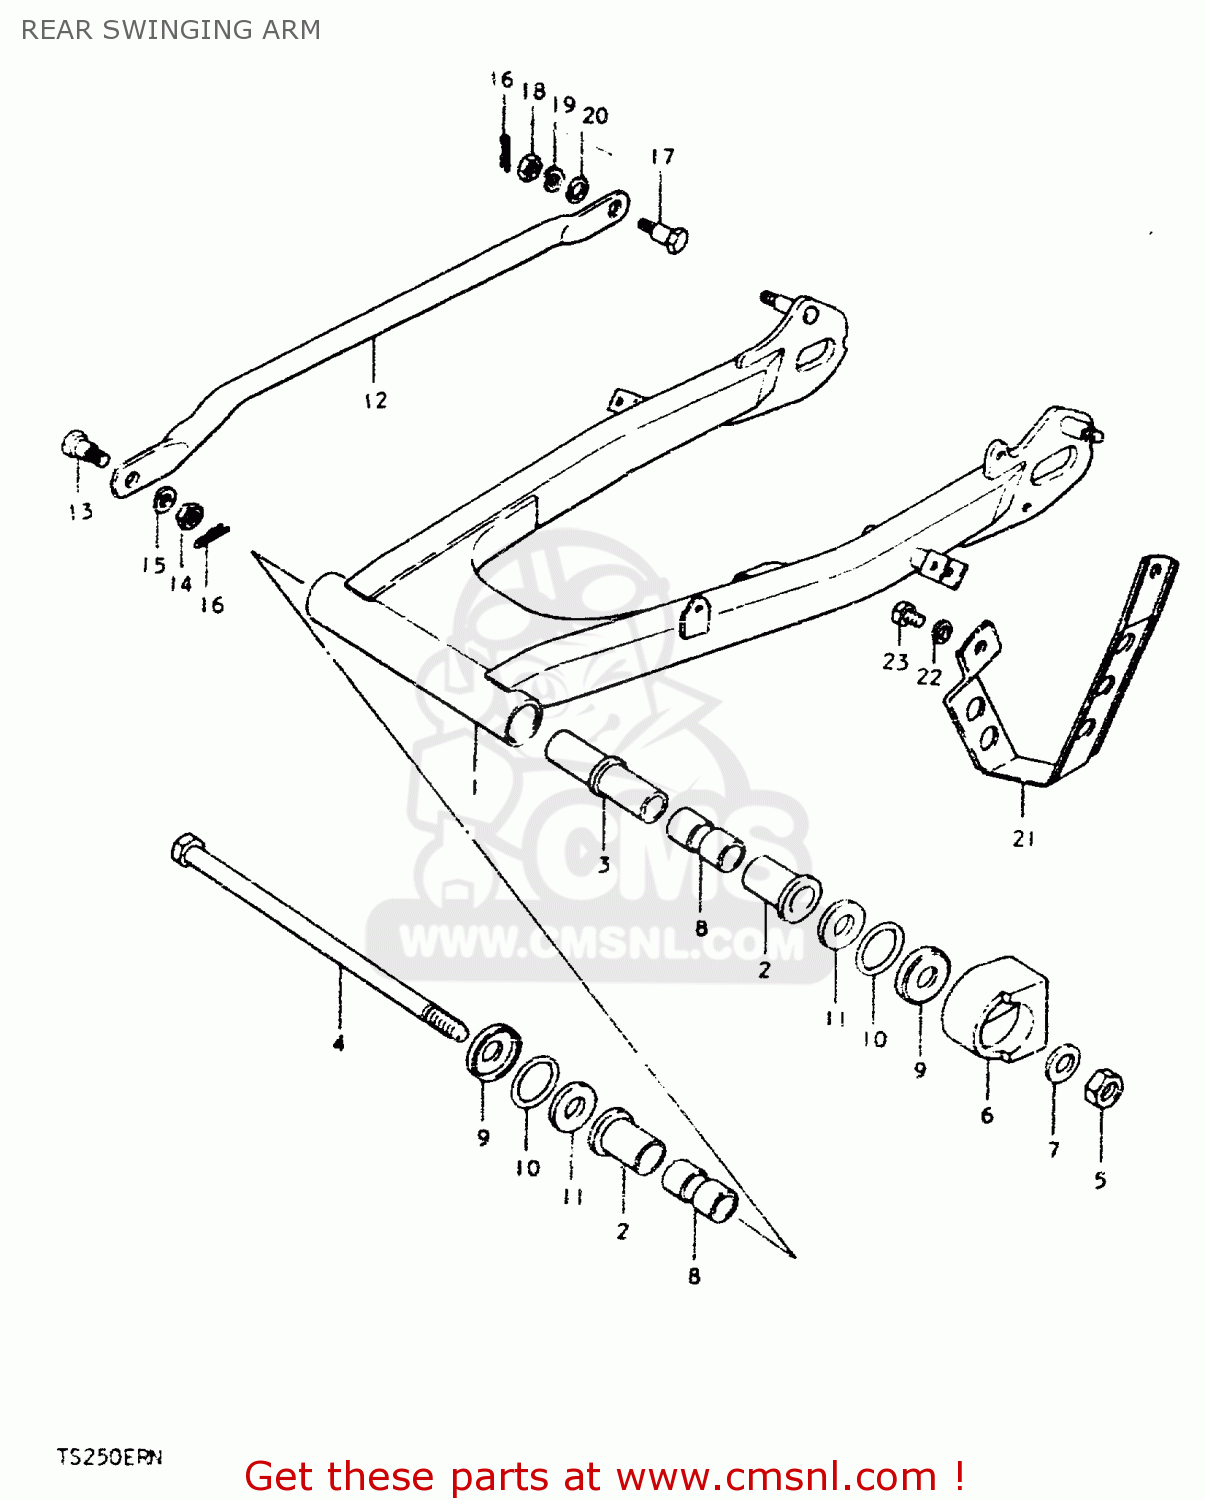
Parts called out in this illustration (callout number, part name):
1	SWING ARM ASSEMBLY,REAR
2	BUSH
3	SPACER,SWING ARM,CENTER
4	SHAFT,REAR SWING ARM
5	NUT 14MM
6	BUFFER,CHAIN TOUCH DEFLECTOR
7	WASHER
8	SPACER
9	COVER
10	O RING(D:3,ID:29.5)
11	WASHER(14.5X29X2.3)
12	TORQUE LINK, REAR
13	BOLT(8X22.5)
14	NUT
15	LOCK WASHER
16	CLIP
17	BOLT(10X32.5)
18	NUT
19	LOCK WASHER
20	WASHER
21	GUIDE,CHAIN
22	LOCK WASHER
23	BOLT 8X12
